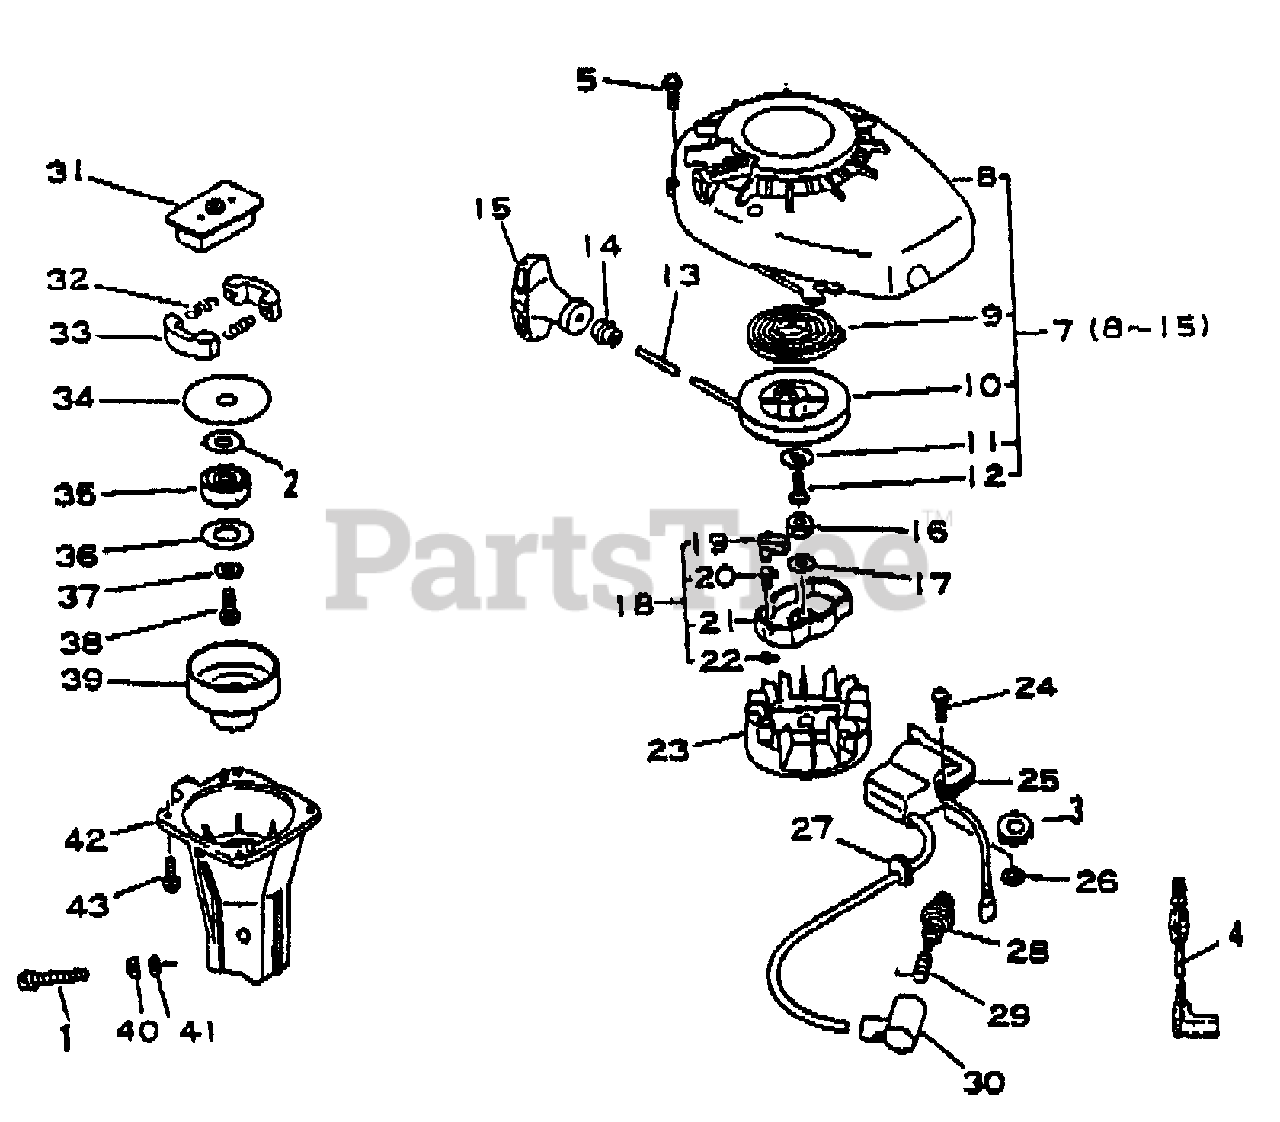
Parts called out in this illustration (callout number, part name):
1	BOLT - 5×25
2	WASHER 10.5×18×1.6
4	LEAD
5	SCREW 4×18
7	STARTER ASSY
8	CASE, STARTER
9	SPRING, RECOIL
10	REEL, ROPE
11	WASHER
13	ROPE, STARTER
14	GUIDE, ROPE
15	GRIP, STARTER
16	NUT 8×1.25
17	WASHER 8.5×16×1.2
18	STARTER PAWL ASSY
19	PAWL, STARTER
20	SPRING, RETURN
21	CATCHER, PAWL
22	E-RING 4
23	FLYWHEEL
24	SCREW 4×22
25	COIL, IGNITION
28	SPARK PLUG - BPM6A
29	TERMINAL, SPARK PLUG
30	CAP, SPARK PLUG
31	HUB, CLUTCH
32	SPRING, CLUTCH
33	SHOE, CLUTCH
34	PLATE, CLUTCH
35	BEARING, BALL 6000-2RLB
37	WASHER 6
38	SCREW 6×12
39	DRUM, CLUTCH
40	WASHER, SPRING 5
41	WASHER, FLAT 5.5×10×0.8
42	CASE, CLUTCH
43	SCREW 4×14
